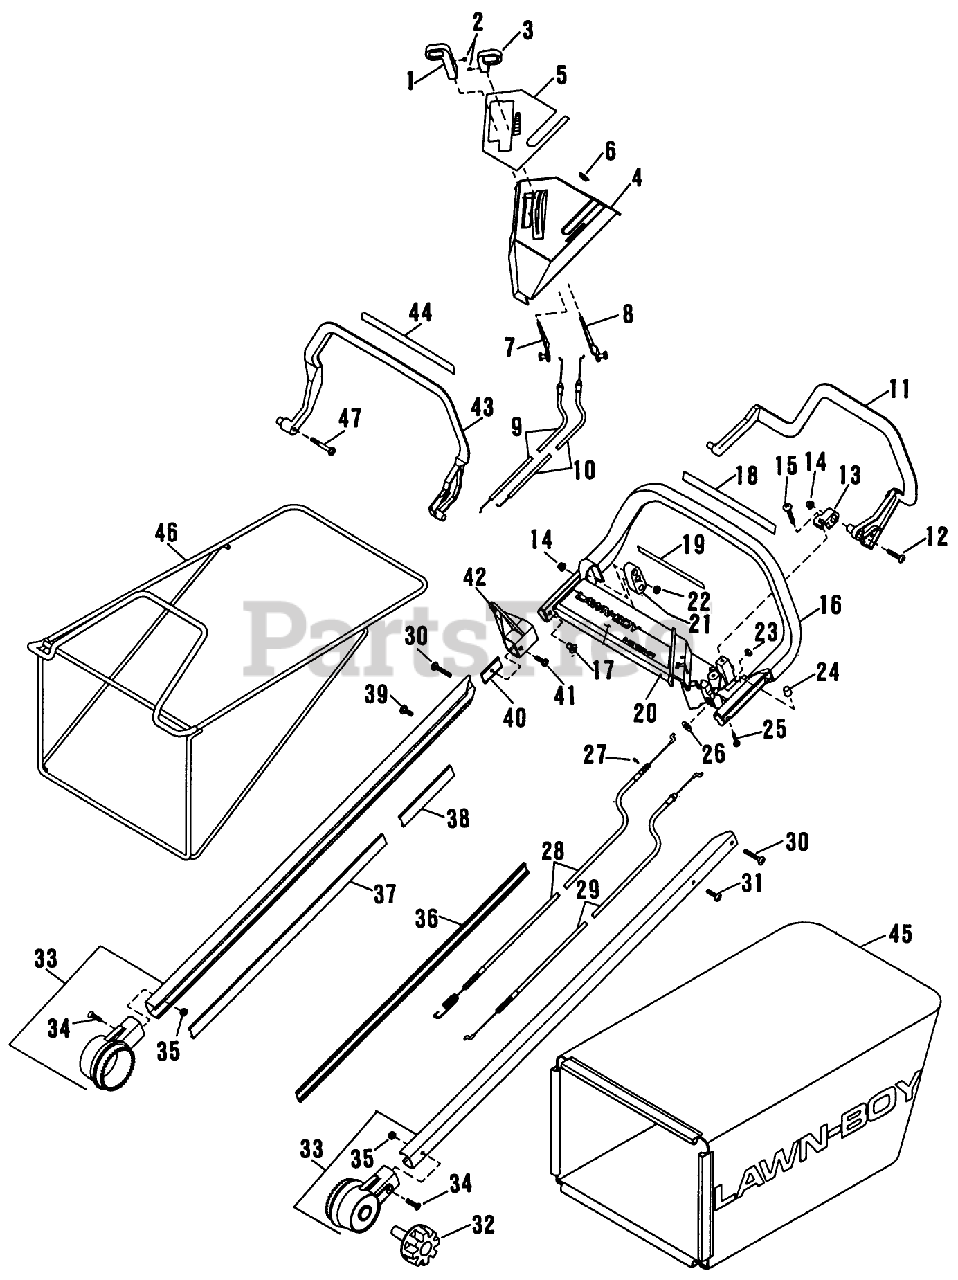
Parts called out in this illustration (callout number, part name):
4	UP COVER & DECAL
9	CABLE AY. WESCON
10	CABLE
11	BAIL-S.P. *
13	PIVOT BAIL PL
14	LOCKNUT FLAN
21	BLOCK BAIL PL
22	LOCKNUT E
29	CABLE ASSEMBLY
30	SCREW-TRUSS
31	SCREW-CROSS RECESS
32	KNOB-HDLE MT.ASM*B
35	LOCKNUT FLAN
40	NUT LB
45	REPL BAG FOR 684190
